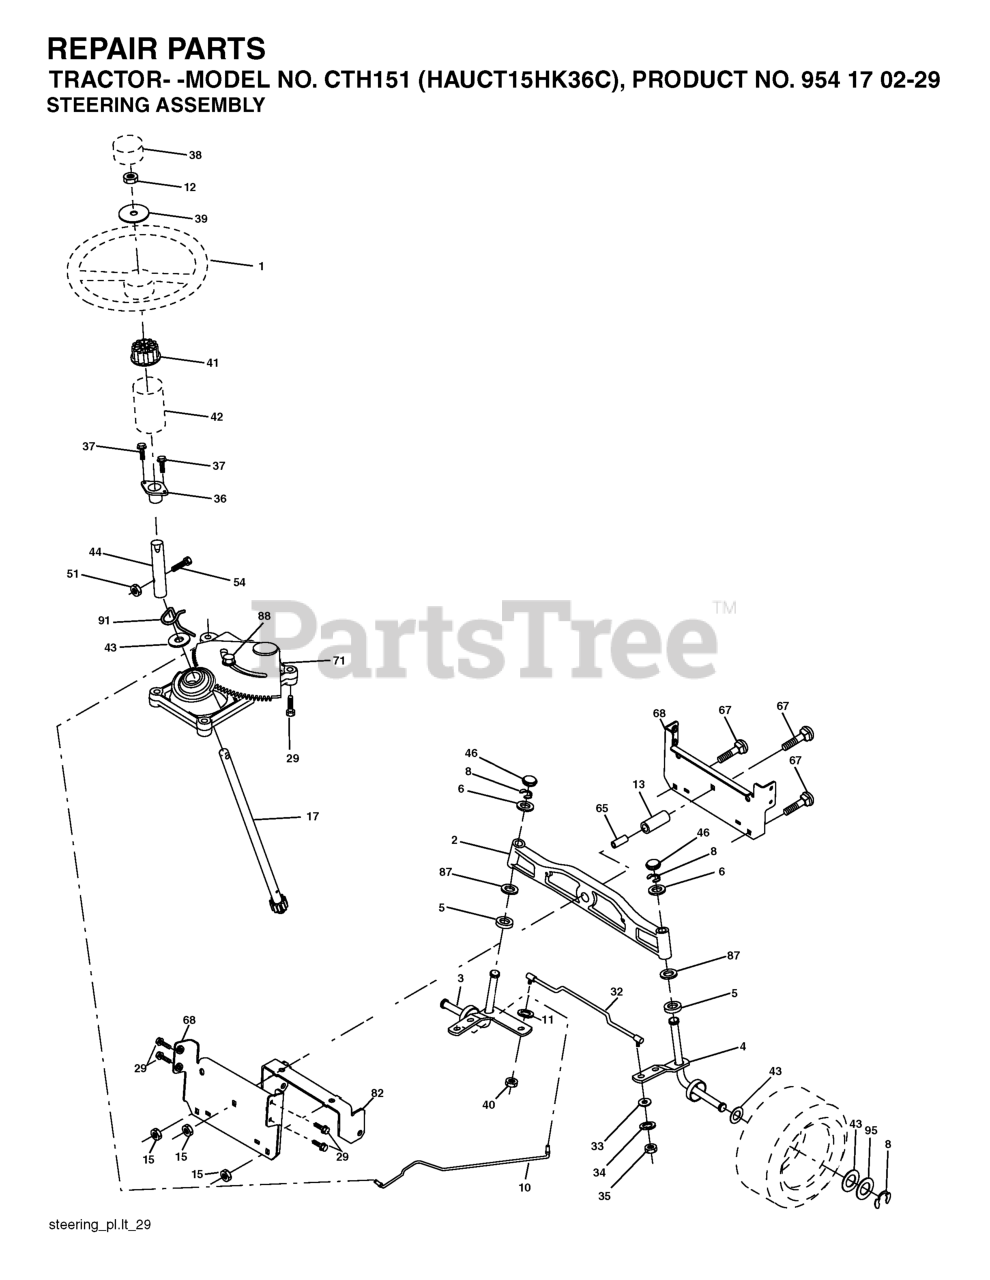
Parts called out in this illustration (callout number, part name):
1	STEERING WHEEL
2	AXLE ASSY FRONT
3	SPINDLE.ASM.LH.15"TIRES
4	SPINDLE.ASM.RH.15"TIRES
5	THRUST WASHER
10	DRAGLINK.15".TIRES.2001
11	WASHER, LOCK 3/8
12	NUT.HEX.1/2-20
13	TUBE, PIVOT AXLE
15	NUT
17	SHAFT ASM, STEERING
29	SCREW, 3/8-16X3/4
32	ROD.ASM.TIE.BALL.JOINT.NOVAN
33	WASHER M
34	WASHER.LOCK.HVY.HLCL.SPR.5/16
35	NUT, CROWNLOCK
36	BUSHING, STEERING
37	SCREW.TT.#10-32X.5.3/8.FLANGE
38	CAP.WHEEL.STEERING.GREY
39	Washer 9/16 ID x 1 1/2 OD 11 Ga. Zin
40	NUT CROWNLOCK 3/8-24
41	STEERING WHEEL ADAPTOR
42	BOOT STEERING
44	EXT, STEERING SHAFT
46	CAP.SPINDLE.BLACK
51	NUT.CROWNLOCK.1/4-28
54	Bolt Hex 1/4-28 unf x 1-1/4 Gr. 8
65	SPACER BRACE AXLE
67	BOLT CARRIAGE
68	BRACE.AXLE.15"TIRES
71	STEERING ASM
82	BRACKET
87	WASHER, FLAT .781 X 1 1/2"
88	BOLT, SHOULDER 7/16-20
91	CLIP.STEERING
95	WASHER.HARDENED
